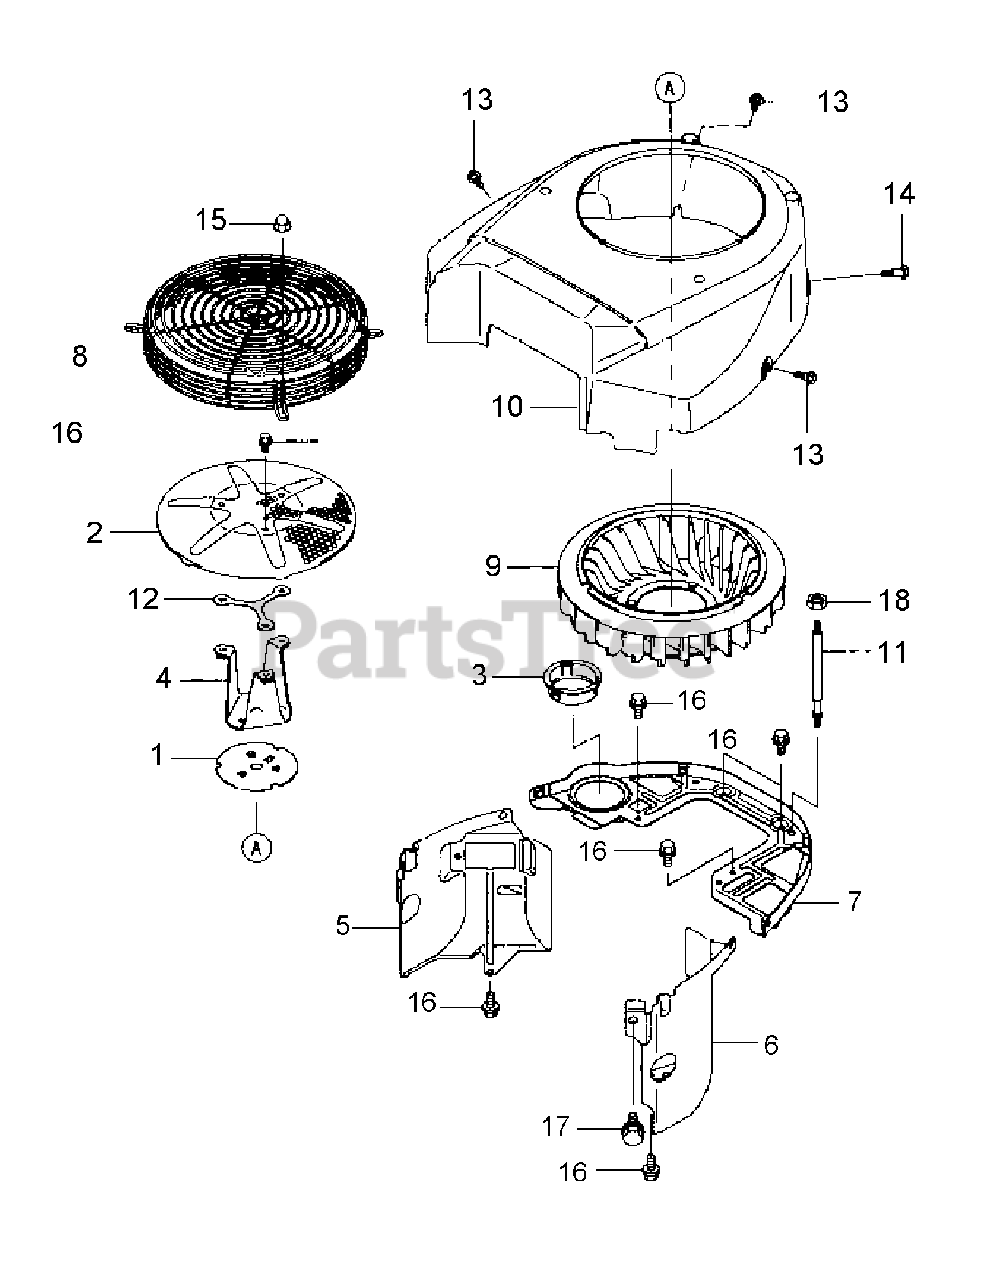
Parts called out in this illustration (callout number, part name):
4	BRACKET
5	ENGINE SHROUD
6	ENGINE SHROUD
7	ENGINE SHROUD
12	SPACER
14	BOLT
16	FLANGED BOLT
17	FLANGED BOLT
